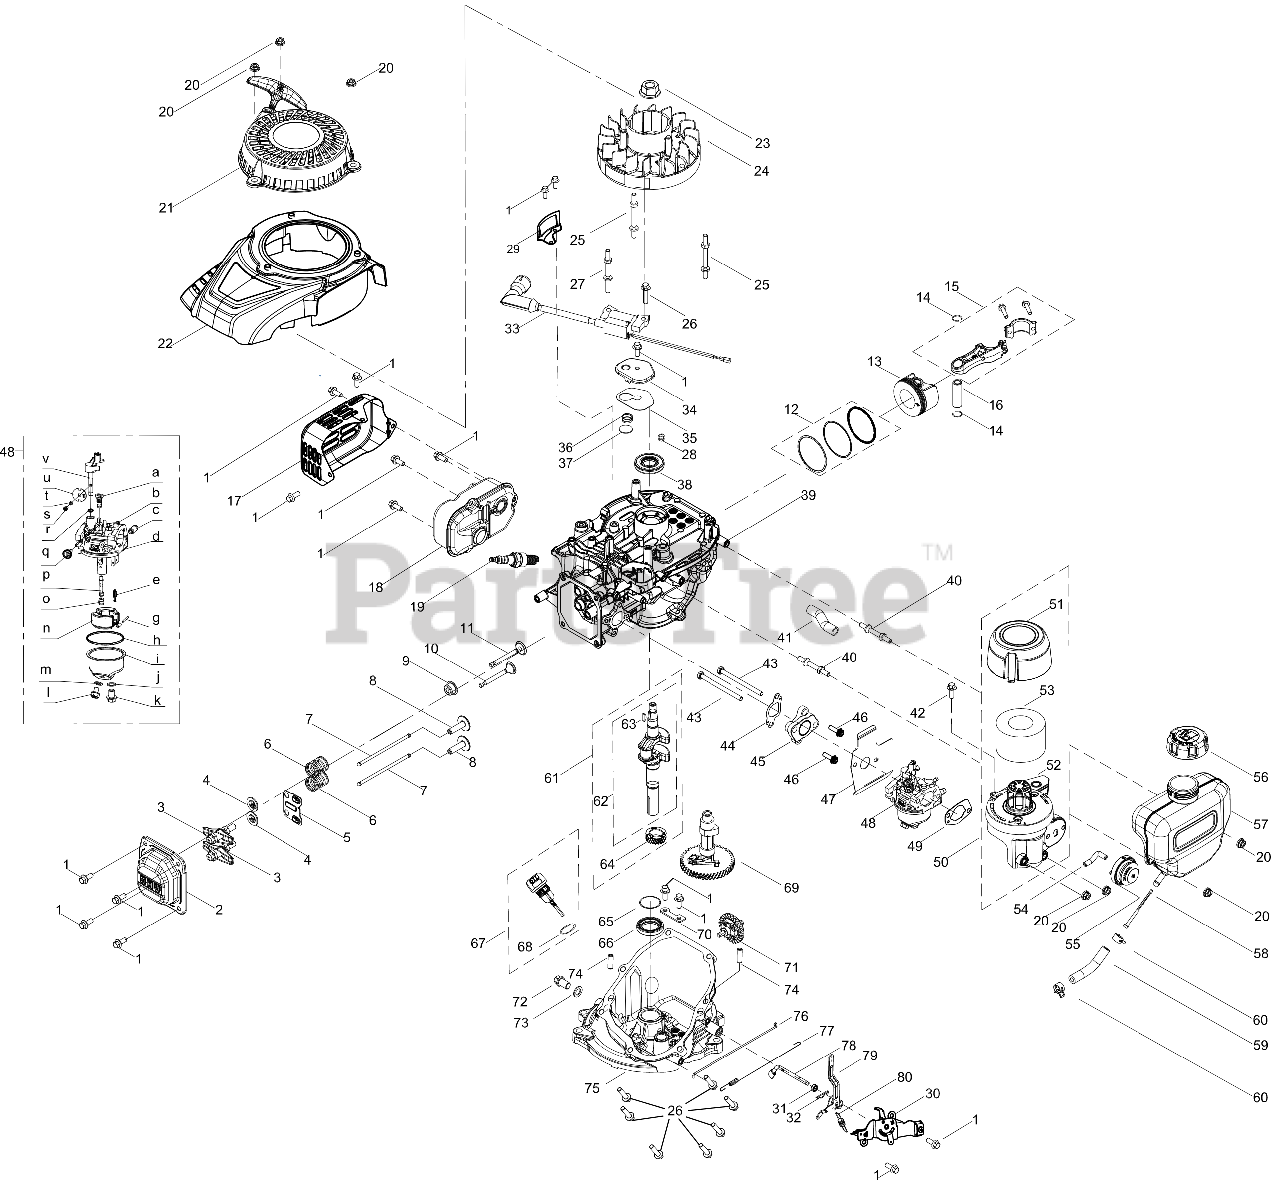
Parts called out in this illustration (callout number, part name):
1	BOLT M6-1 x 14 GR8.8
2	VALVE COVER
3	ROCKER ARM ASSEMBLY
4	VALVE SPRING RETAINER
5	PUSH ROD GUIDE
6	VALVE SPRING
7	PUSH ROD GUIDE
8	TAPPET (LIFTER)
9	INTAKE VALVE SEAL
10	EXHAUST VALVE
11	INTAKE VALVE
12	PISTON RING SET
14	SNAP RING-PISTON PIN
15	CONNECTING ROD ASSEMBLY
16	PISTON PIN
17	MUFFLER GUARD
19	SPARK PLUG
21	STARTER RECOIL ASSEMBLY
22	SHROUD ASSEMBLY
23	FLYWHEEL NUT
24	FLYWHEEL
25	STUD M6 x 75
26	BOLT M6-1 x 25 GR8.8
27	STUD M6 x 73
29	COVER PLATE
30	VARIABLE SPEED CONTROL
31	GOVERNOR SEAL
32	COTTER PIN
33	IGNITON COIL
34	BREATHER COVER PLATE
35	BREATHER GASKET
36	BREATHER VALVE SPRING
37	BREATHER VALVE
38	UPPER CRANKSHAFT SEAL
40	FUEL TANK MOUNTING STUD M6X59.5
41	BREATHER HOSE
42	BOLT M6 x 16
43	BOLT M6X80
44	CARBURETOR INSULATION GASKET
45	CARBURETOR INSULATOR
46	BOLT M6X20
47	CARBURETOR GASKET
48	CARBURETOR ASSEMBLY KM-1R61BA
49	AIR FILTER BASE GASKET
50	AIR FITLER ASSEMBLY
51	AIR FILTER COVER
52	AIR FILTER BASE
53	AIR FILTER - FOAM
54	PRIMER HOSE
55	VENTED PRIMER ASSEMBLY
56	FUEL CAP ASSEMBLY
57	FUEL TANK ASSEMBLY
58	FUEL FILTER
59	FUEL HOSE
60	HOSE CLAMP
61	CRANKSHAFT ASSEMBLY
62	CRANKSHAFT
63	FLYWHEEL KEY
64	CRANKSHAFT TIMING GEAR
65	THRUST WASHER
66	LOWER CRANKSHAFT SEAL
67	DIPSTICK ASSEMBLY
68	DIPSTICK SEAL
69	CAMSHAFT ASSEMBLY
70	GOVERNOR GEAR MOUNTING PLATE
71	GOVERNOR GEAR/SHAFT ASSEMBLY
72	OIL DRAIN PLUG
73	WASHER
74	DOWEL PIN 7X20
75	CRANKCASE COVER
76	THROTTLE LINKAGE
77	THROTTLE LINKAGE SPRING
78	GOVERNOR ARM SHAFT
79	GOVERNOR ARM ASSEMBLY
80	GOVERNOR SPRING
